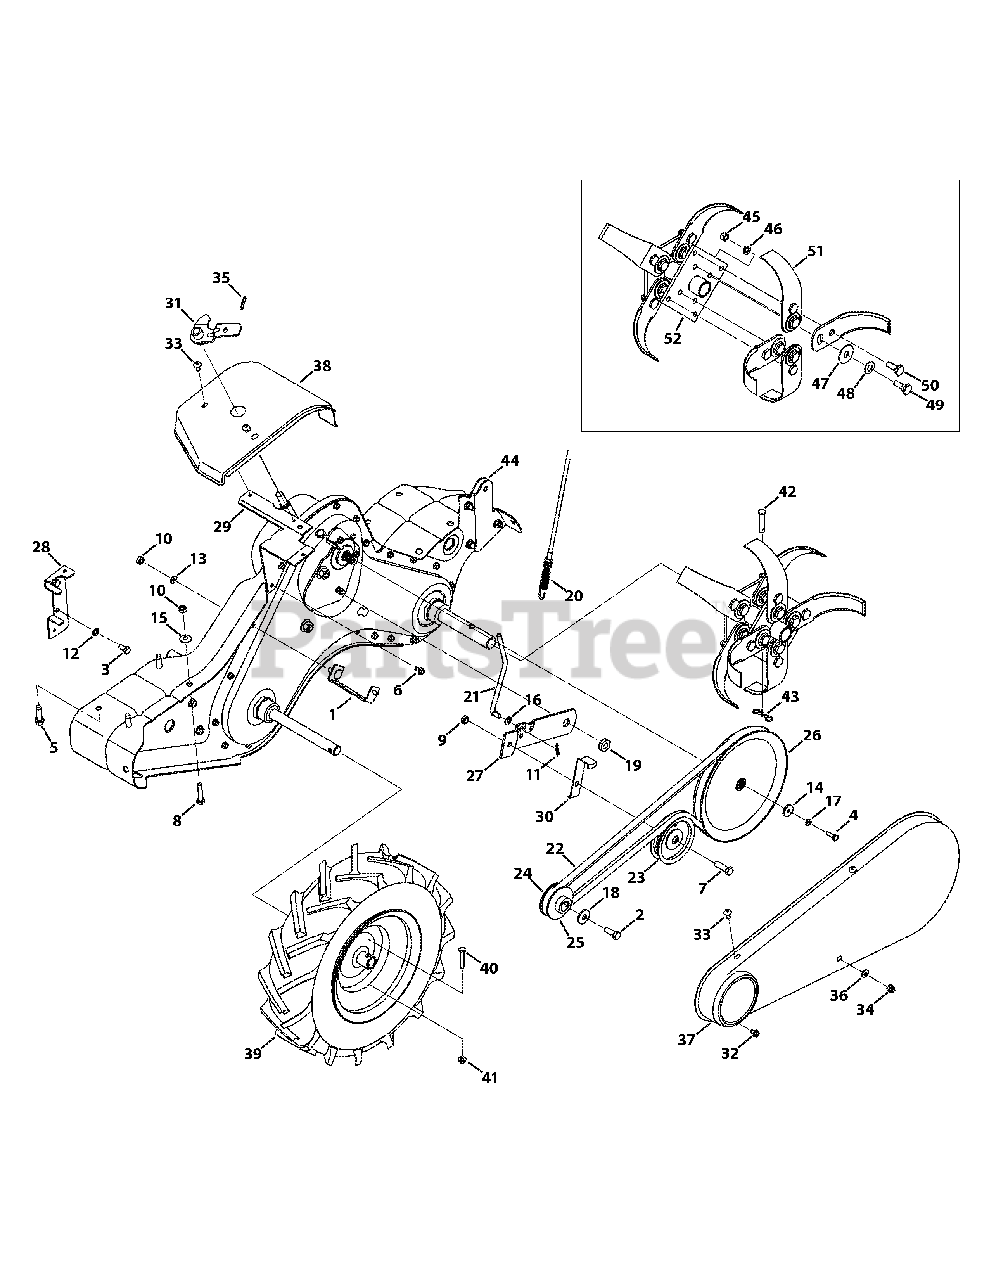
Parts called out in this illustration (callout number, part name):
1	Belt Cover Bracket Assembly
2	Hex Head Screw, 3/8-24 x 1.00
3	Hex Head Screw, 5/16-24 x .625
4	Hex Head Screw, 1/4-28 x .75
5	Screw, 3/8-16 x 1.250
6	Screw, 1/4-20 x 0.500
7	Hex Head Screw, 3/8-16 x 1.25
8	Hex Head Screw, 5/16-18 x 1.50
9	Jamlock Nut, 3/8-16
10	Hex Nut, 5/16-18
11	Cotter Pin, .072 DIA. x 1.13 LG
12	Washer, Lock, 5/16
13	Washer, Lock, 5/16
14	Washer, Flat, .265 x .938 x .120
15	Washer, Bell, .340 x .872 x .060
16	Washer, Spring, .317 x .625 x .020
17	Washer, Lock, 1/4
18	Washer, Bell, .396 x 1.140 x .095
19	Shoulder Nut, 7/16-20
20	Clutch Cable
21	Idler Pulley Rod
22	Belt, 4L x 58.16 LG
23	Flat Idler Pulley w/ Flanges, 3.75 O.D.
24	Engine Pulley, Inner Half
25	Engine Pulley, Outer Half
26	Input Pulley, 4L x 8.594
27	Idler Pulley Bracket
28	Belt Keeper Bracket, B&S 6.5 HP
29	Shaft Cover Bracket
30	Idler Belt Keeper
31	Shaft Crank Assembly
32	Screw, 1/4-20:0.375
33	Screw, 1/4-14:0.625
34	Lock Nut, Cap, 1/4-28
35	Spiral Pin, 3/16 x 1.00
36	Washer, Flat, .271x .630 x .065
37	Belt Cover - Gray
37	Belt Cover - Black Jack
38	Shaft Cover
39	Wheel, 16 x 4.6 x 8
40	Hex Head Screw, 1/4-20 x 1.50
41	Flangelock Nut, 1/4-20
42	Clevis Pin, .375 x 1.75
43	Cotter Pin, Bow-Tie
44	Complete Gear Case Assembly
45	Hexlock Nut, 3/8-24
46	Washer, Lock, 3/8
47	Washer, Flat, .51 x 1.5 x 0.07
48	Washer, Bell, .525 x 1.00 x .050
49	Screw, Shoulder, 3/8-24 x 1/2 x .325
50	Screw, Shoulder, 3/8-24 x 1/2 x .180
51	Articulating Tine
52	Tine Adaptor Assembly
52	Tine Assembly
